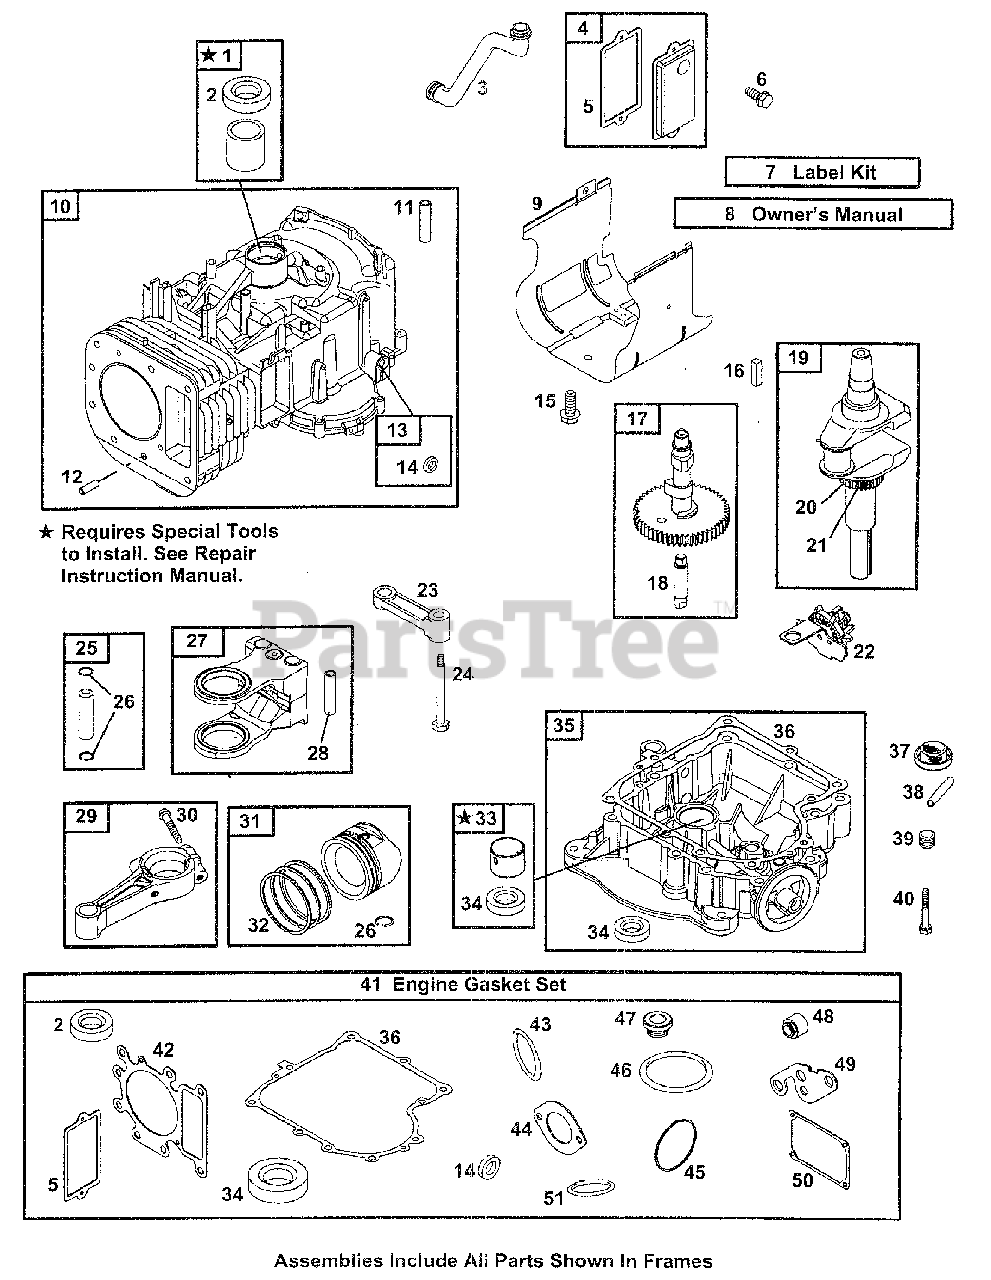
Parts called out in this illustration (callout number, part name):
1	Bushing/Seal Kit (Magneto Side)
2	Oil Seal
3	Breather Tube
4	Breather Assembly
5	Breather Gasket
6	Screw (Breather Assembly)
8	Owner's Manual
9	Cylinder Shield
10	Cylinder Assembly
11	Counterweight Pin
12	Locating Pin
13	Governor Crank Bushing
14	Governor Shaft Seal
15	Screw (Cylinder Shield)
16	Flywheel Key
17	Camshaft
18	Pump Shaft
19	Crankshaft
20	Timing Gear
21	Timing Key
22	Governor/Oil Slinger
23	Counterweight Link
24	Screw (Counterweight)
25	Piston Pin (Standard)
26	Piston Pin Lock
27	Counterweight
28	Counterweight Pin
29	Connecting Rod (Standard)
30	Screw (Connecting Rod)
31	Piston Assembly (Standard)
32	Ring Set (Standard)
33	Bushing/Seal Kit (PTO Side)
34	Oil Seal
35	Engine Sump
36	Crankcase Gasket (.015 Thick, Std)
37	Oil Pump Screen
38	Oil Pump Tube
39	Oil Drain Plug
40	Screw (Engine Sump)
41	Engine Gasket Set
42	Cylinder Head Gasket
43	O-Ring Seal (Air Cleaner Base)
44	Intake Gasket
45	O-Ring Seal (Intake Manifold)
46	O-Ring Seal (Oil Pump Cover)
47	Dipstick Tube Seal
48	Valve Seal
49	Oil Adapter Gasket
50	Rocker Cover Gasket
51	Dipstick/Tube Seal
